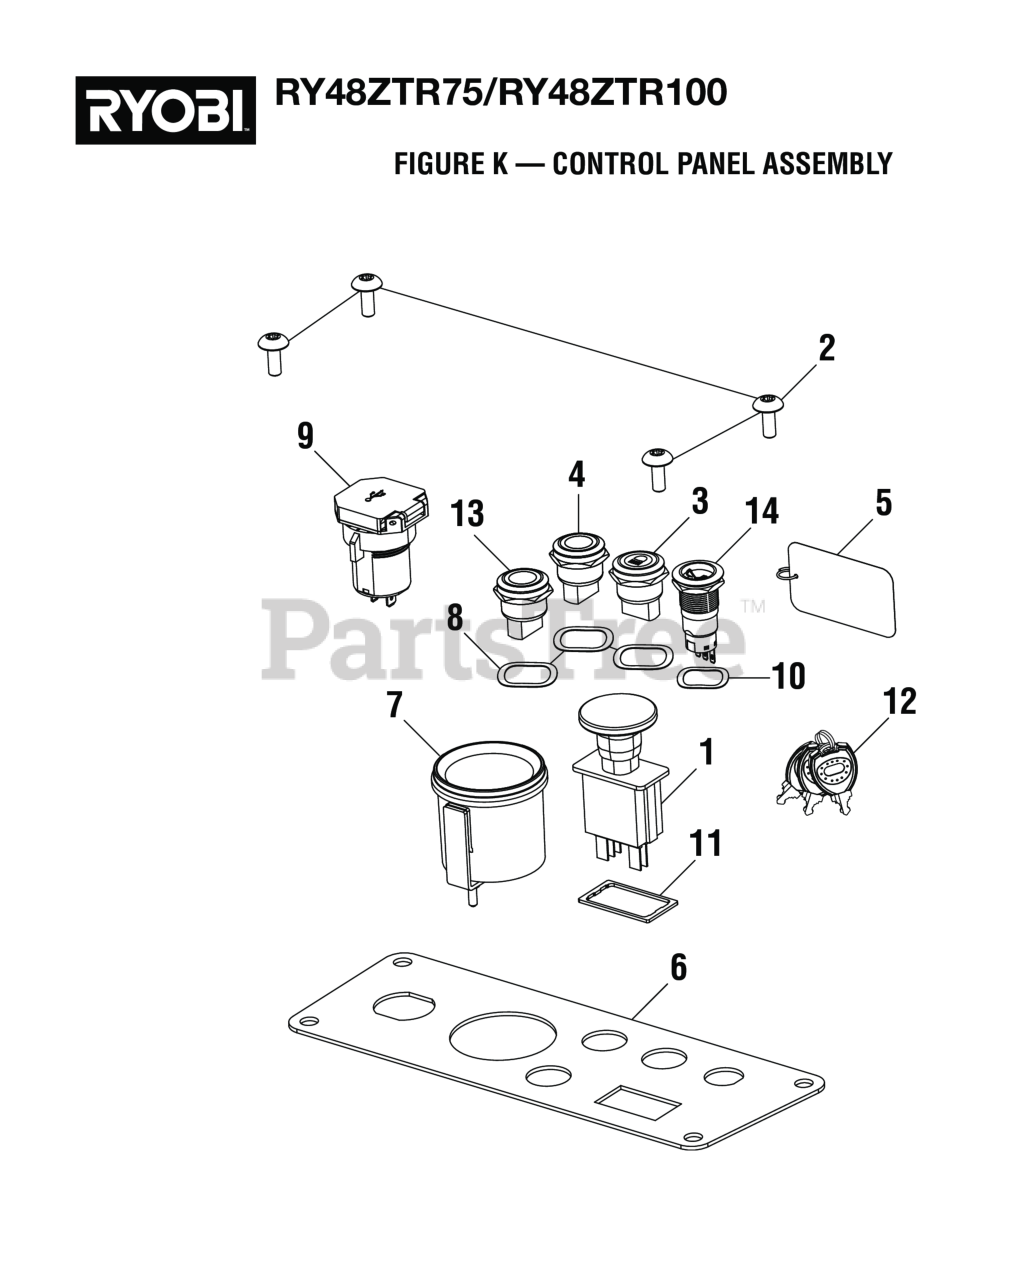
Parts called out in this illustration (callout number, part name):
1	Power Take Off Button (PTO)
2	Screw (M6 x 10 mm, Soc. Button Hd.)
3	Light Switch
4	Button Switch, Drive Speed
5	Watch For Kids, Keychain Label
6	Control Panel Face Plate
7	Fuel Gauge, ZTR
8	Wavy Washer
9	USB Module
10	Wavy Washer
11	PTO Gasket
13	Button Switch, Blade Speed
14	Switch Key Module
